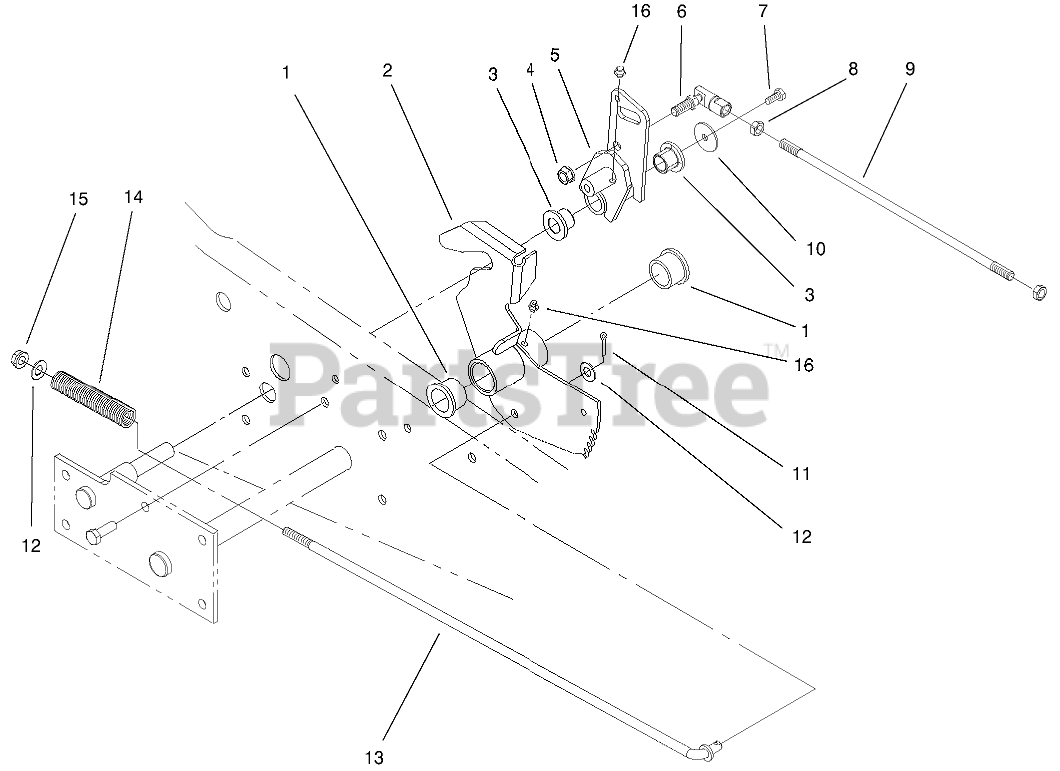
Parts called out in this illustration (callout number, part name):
1	BUSHING-FLANGED
2	PLATE-PIVOT, BRAKE
3	BUSHING
4	NUT-LOCK
5	PIVOT-HYDRO
6	END-TIE ROD, LH
7	SCREW-HH
8	NUT-JAM, LH
9	ROD-PIVOT TO PEDAL
10	WASHER-FLAT
11	PIN-COTTER
12	WASHER-FLAT
13	ROD-BRAKE
14	SPRING-COMPRESSION
15	NUT-LOCK, NI
16	FITTING-GREASE
